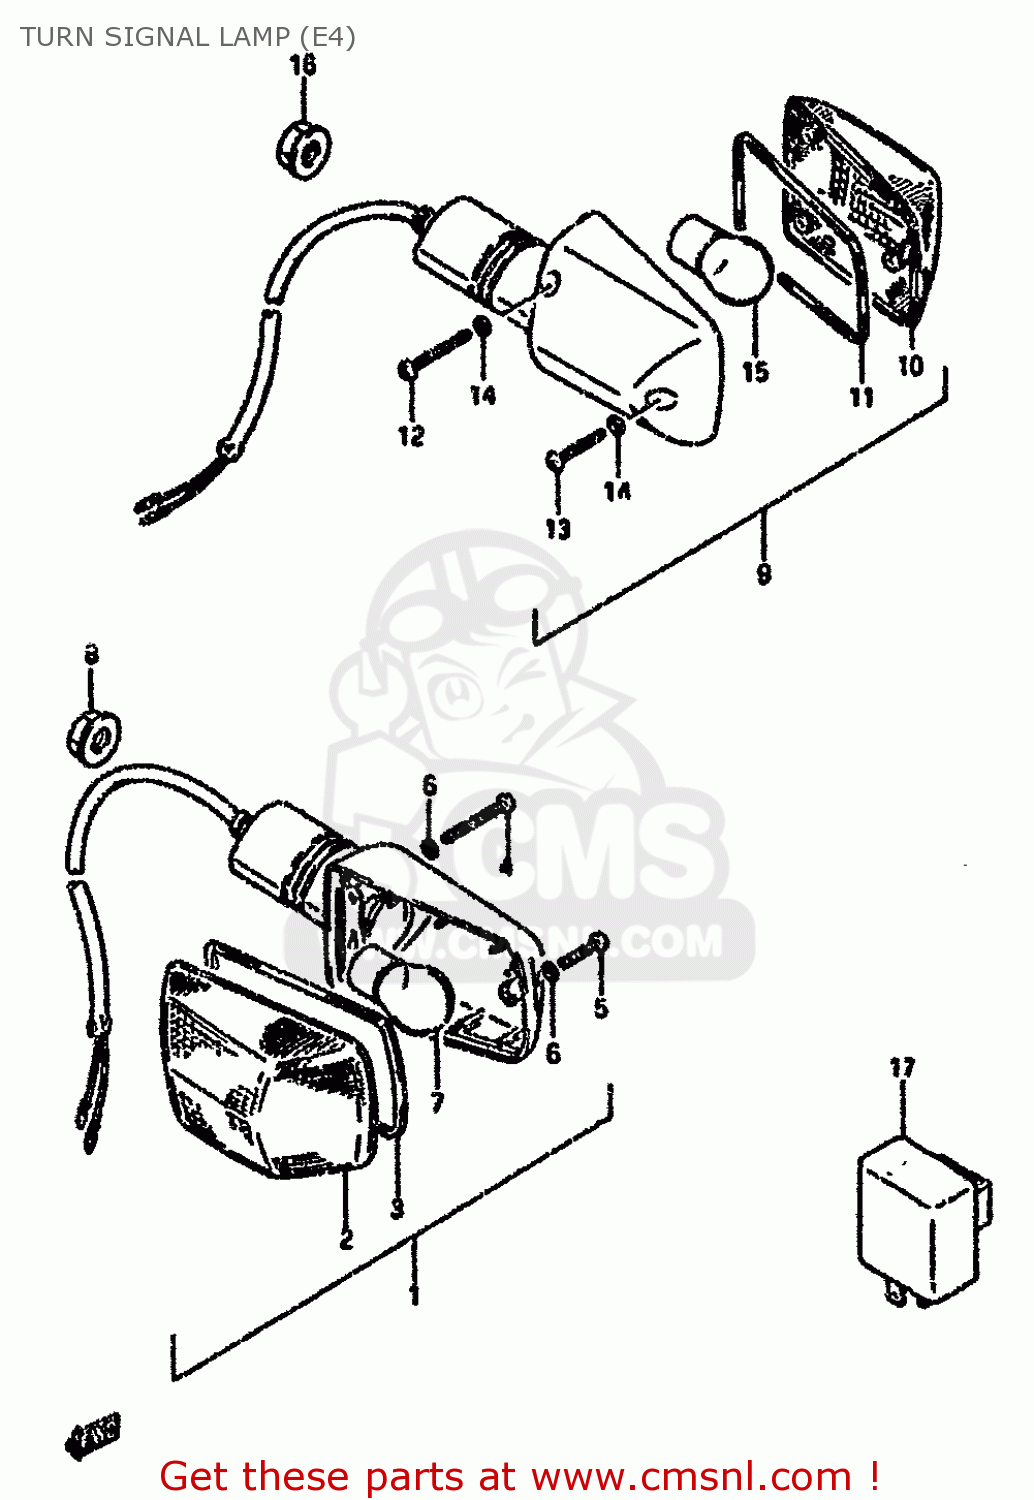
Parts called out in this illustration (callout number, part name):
1	LAMP ASSY,REAR TURN SIGNAL
2	LENS,TURNSIGNAL
3	GASKET (NAS)
4	SCREW(3X30)
5	SCREW
6	GASKET (NAS)
7	BULB 12V 21W
8	NUT
9	LAMP ASSY,REAR TURN SIGNAL
10	LENS,TURNSIGNAL
11	GASKET (NAS)
12	SCREW(3X30)
13	SCREW
14	GASKET (NAS)
15	BULB 12V 21W
16	NUT
17	RELAY ASSEMBLY,TURN SIGNAL
